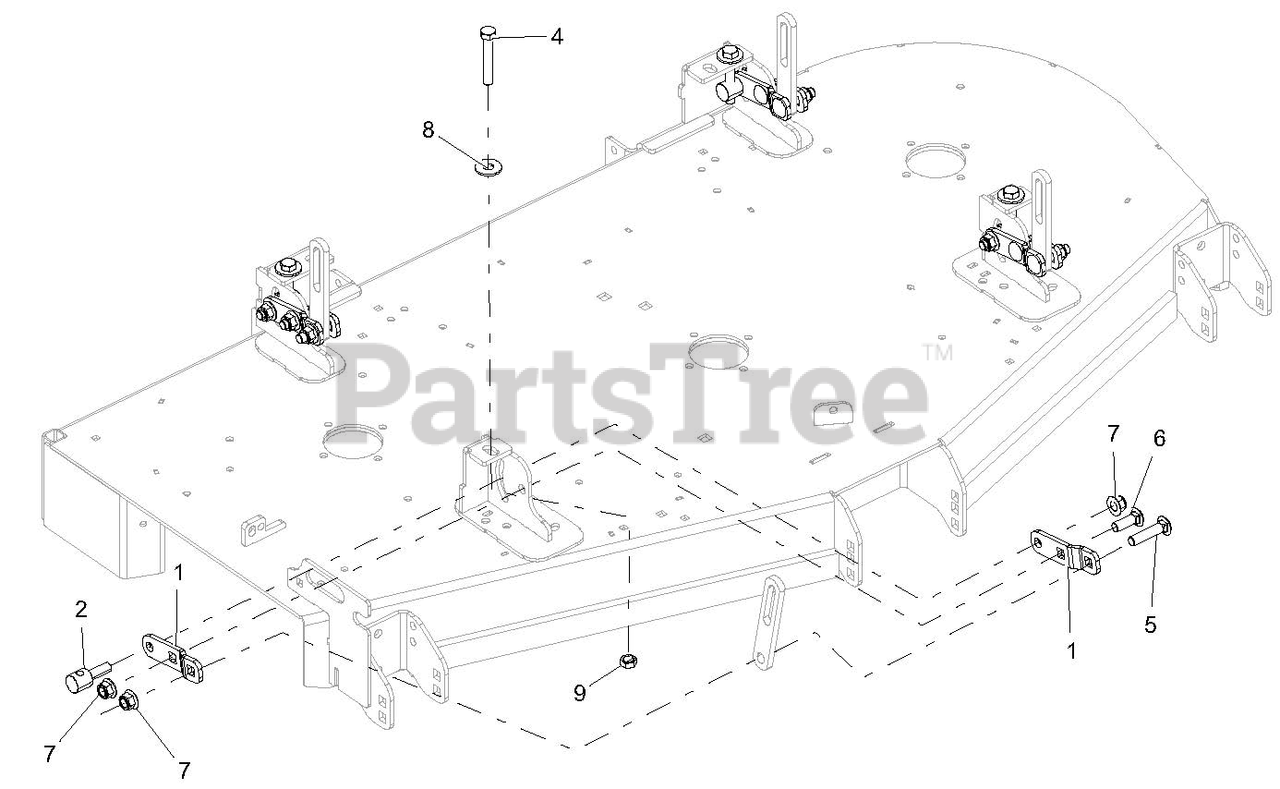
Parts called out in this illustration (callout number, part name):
1	BRKT, DECK LEVELING-BLACK
2	TRUNNION, .50-13
4	BLT-HEX .50-13X3.00 GR5 FTH YWZC
5	BLT-RDHDSQNK .50-13X2.25 G5Y
6	BLT-RDHDSQNK .50-13X1.50 G5 YWZC
7	NUT-LK-NYL-FLG .50-13 YWZC
8	WSHR-FL-STL.563X1.38X.109YWZC
9	NUT, JAM .500-13 YWZC
